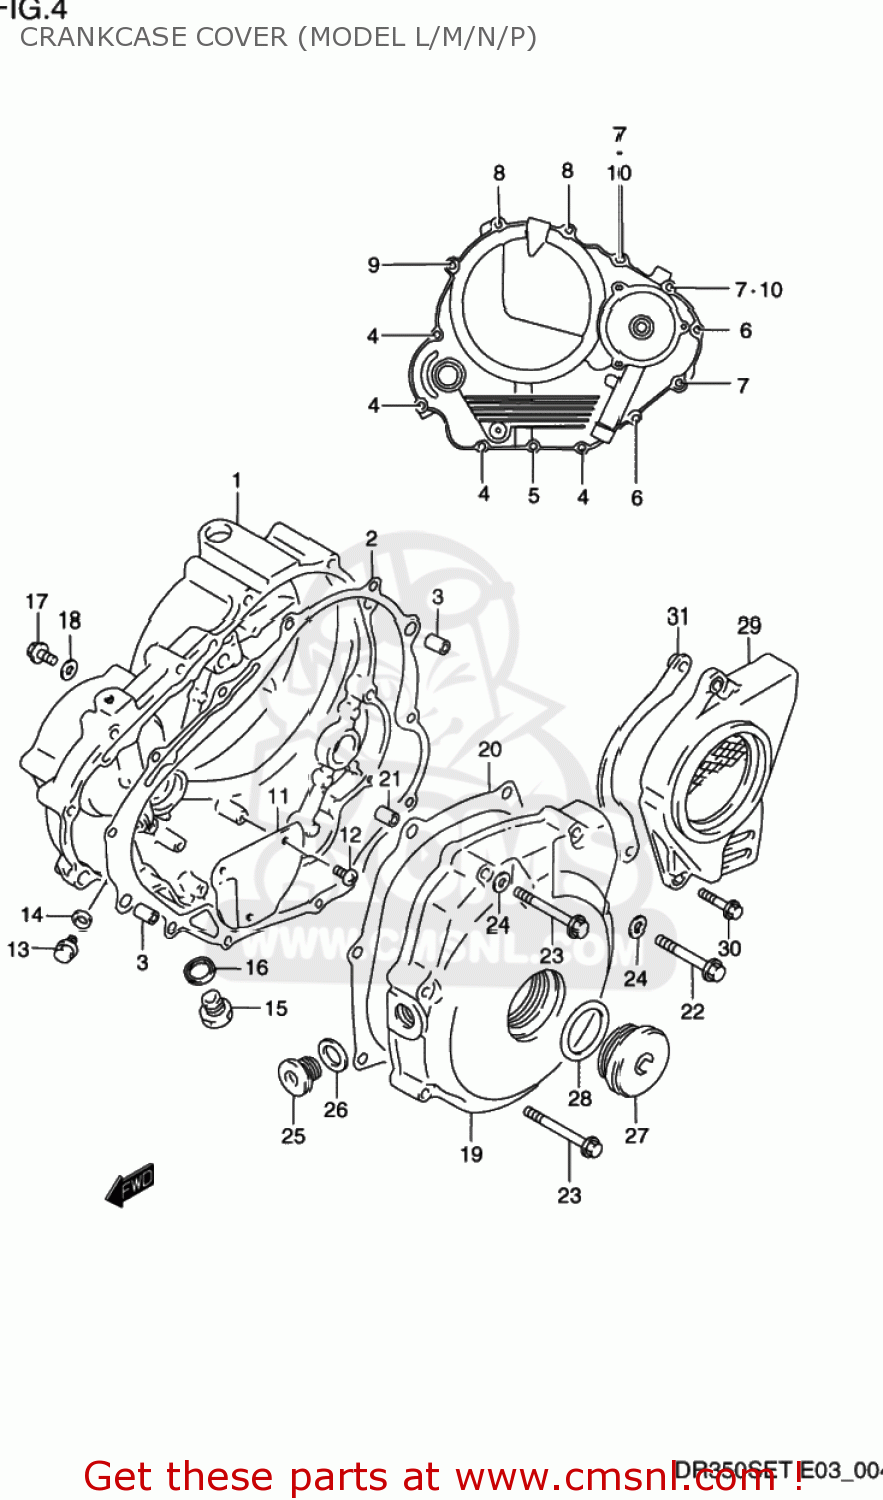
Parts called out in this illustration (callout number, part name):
1	COVER,CLUTCH
2	GASKET,CLUTCH COVER (NAS)
3	PIN
4	BOLT
5	BOLT
6	BOLT
7	BOLT
8	BOLT
9	BOLT
10	GASKET(5.8X13X1.2) (NAS)
11	SEPARATOR,OIL RETURN
12	SCREW(5X10)
13	BOLT(6X8)
14	GASKET(6.2X11X1).2 (NAS)
15	PLUG,14X12
16	GASKET(14X19.2X2) (NAS)
17	SCREW (6X10)
18	GASKET(5.8X13X1.2) (NAS)
19	COVER,MAGNETO
20	GASKET,MAGNETO COVER (NAS)
21	PIN
22	BOLT
23	BOLT
24	GASKET(5.8X13X1.2) (NAS)
25	PLUG,14X12
26	GASKET(14X19.2X2) (NAS)
27	PLUG(SILVER)
28	O RING(D:3.1,ID:32.7)
29	COVER,ENGINE SPROCKET
30	BOLT
31	PLATE,FR CHAIN GUIDE
